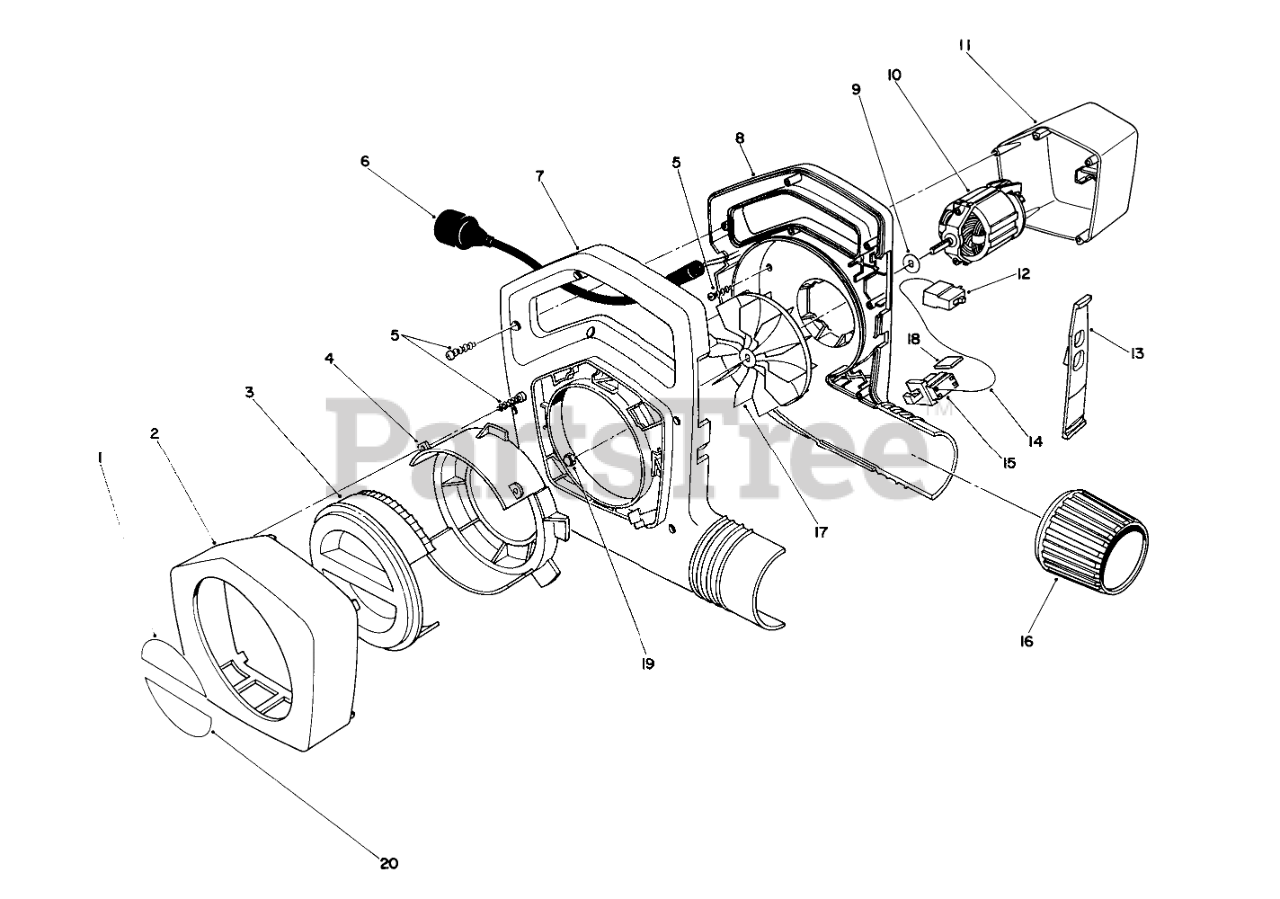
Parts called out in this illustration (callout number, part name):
1	Decal-Upper Choke (Model No. 51535)
1	DECAL, UPPER CHOKE, 550
2	Ring-Trim
3	Adjuster-Choke
4	Ring-Tab
5	Screw
6	Cord-Power Supply
7	BLOWER HOUSING, RH
8	Housing-L.H.
9	Washer-Impeller
10	Motor
10	MOTOR, BLOWER (450/550)
11	HOT STAMPED MOTOR COVER
11	Cover-Motor
12	Switch-On/Off
12	Switch-Two Speed (Model 51545)
13	Cam-Switch-On/Off
13	HOT STAMPED CAM SWITCH
14	WIRE -INTERNAL
15	SWITCH-INTERLOCK
16	Collar-Output
17	Impeller
17	IMPELLER-NEW STYLE
18	NEW STYLE DUST PLUG
19	NUT-LOCK, CAP
20	DECAL, LOWER CHOKE, 450
20	DECAL, LOWER CHOKE, 550
